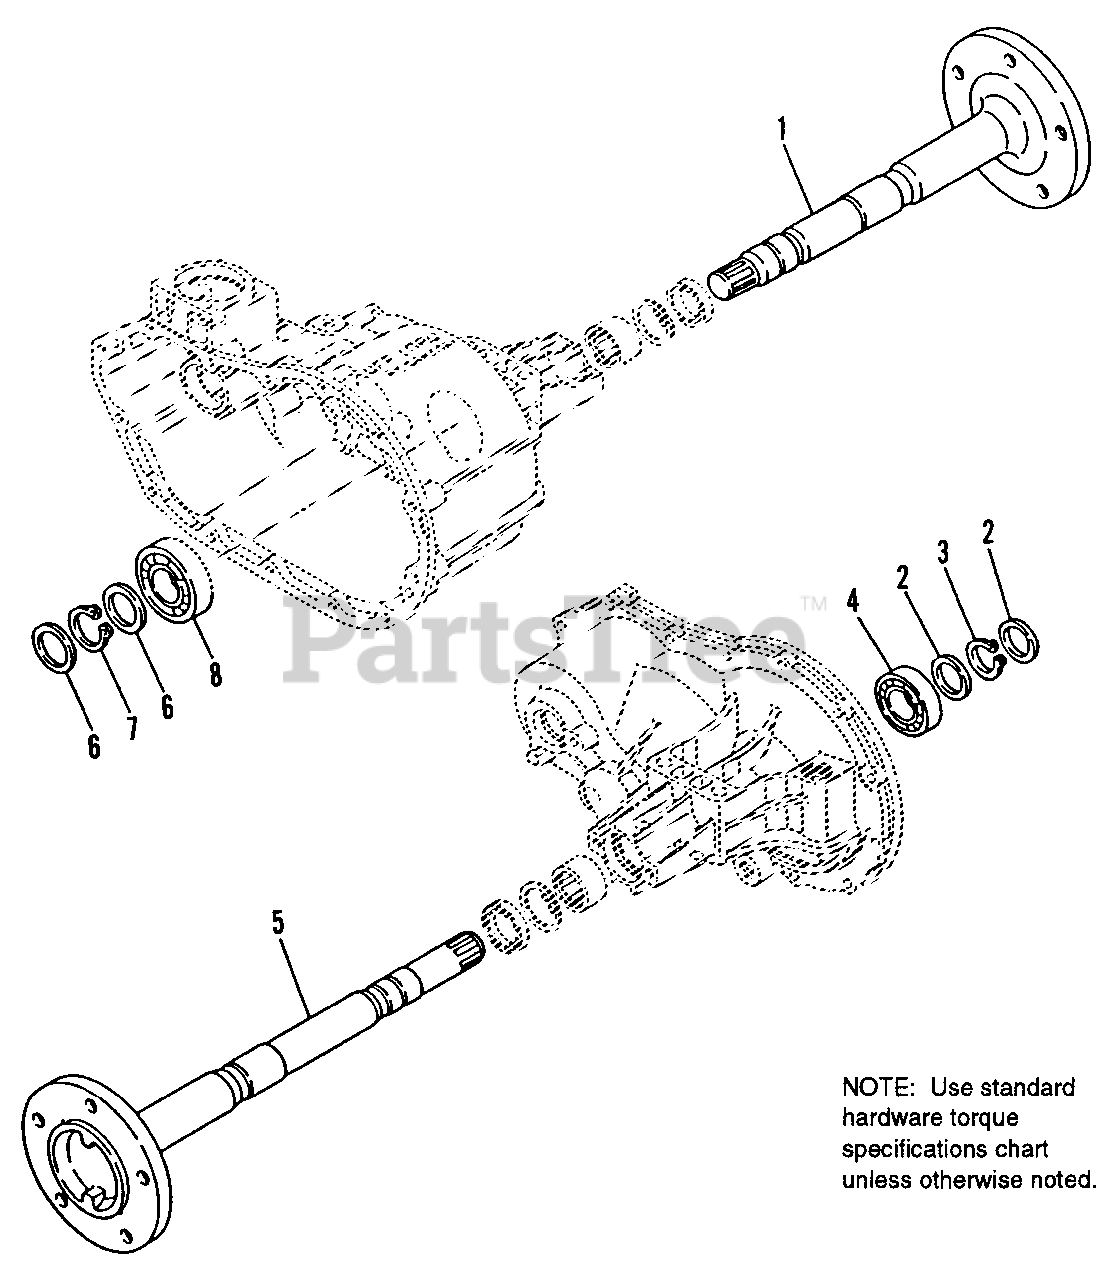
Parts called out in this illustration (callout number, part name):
1	SHAFT, Axle, R.H.
3	RING, Internal Snap
5	SHAFT, Axle, L.H.
7	RING, Internal Snap
